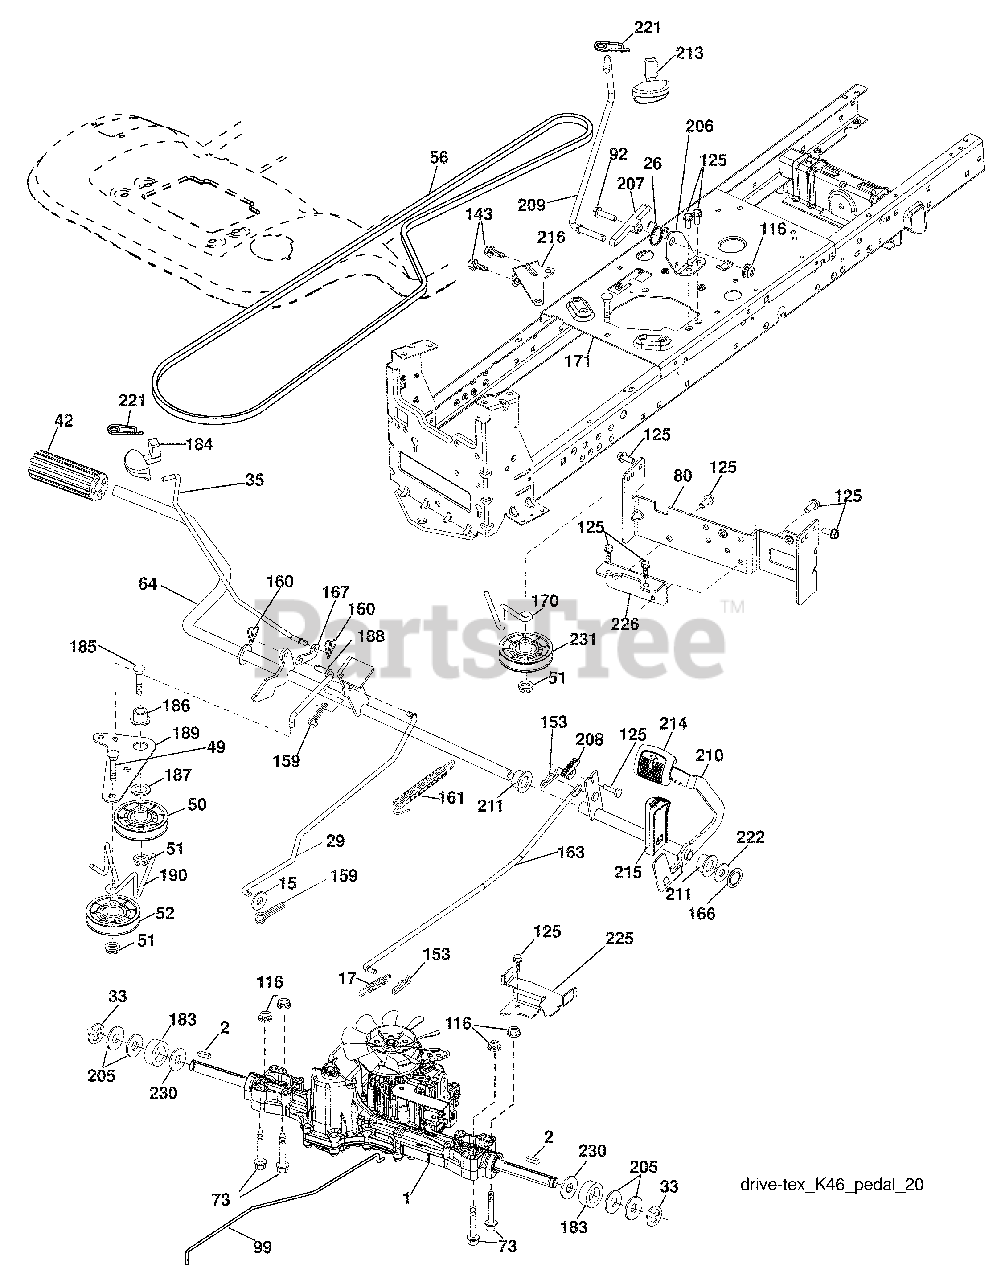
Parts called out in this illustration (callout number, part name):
1	Transaxle, TUFFTORQ K46
2	Key Square
15	Washer 13/32 x 13/16 x 16 Ga.
17	Spring, Brake
26	Spring Return Cruise
29	Rod, Brake
35	Rod, Brake, Park
42	Cover, Foot Pedal
50	Pulley Idler Flat
51	Lock Nut 3/8-16
52	Idler V-Groove 910" Offset
56	V-Belt, Drive
64	Shaft Asm. Pedal Brake Control
73	Bolt Hex 5/16-18 Gr. 5
80	Strap Torque
92	Bolt Fin Hex 5/16-18 unc x 1.25
99	Rod Spring Bypass
116	Nut Lock Hex Flange 5/16-18
125	Screw 5/16-18 x 3/4
143	Screw 5/16-18 x 1/2
153	Retainer Spring
159	Pin Cotter 1/8 x 3/4
160	Retainer Clip
161	Spring, Return, Clutch
163	Rod Pedal Control
166	Nut Push
167	Latch Brake Parking
170	Keeper Belt Centerspan
183	Spacer Axle
184	Handle Parking Brake
186	Spacer Retainer
187	Washer
188	Link Clutch Ground Drive
189	Bellcrank Ground Drive
190	Keeper Bellcrank Ground Drive
205	Washer 25/32 x 1-5/8 16 Ga.
206	Bracket Mount Latch Cruise
207	Latch Control Cruise
208	Gear Sector Control Cruise
209	Rod Control Cruise
210	Rockr Asm. Pedal Control
211	Bearing Nylon
213	Knob control Cruise
214	Pad Pedal Forward
215	Pad Pedal Reverse
216	Bracket Pulley Idler
221	Retainer Spring Clip
222	Washer 21/32 x 1-1/4 10 Ga.
225	Keeper Bolt Transaxle
226	Bracket Mount Torque
230	Washer Hardened
231	Idler V-Groove 1.688" OFFSET
